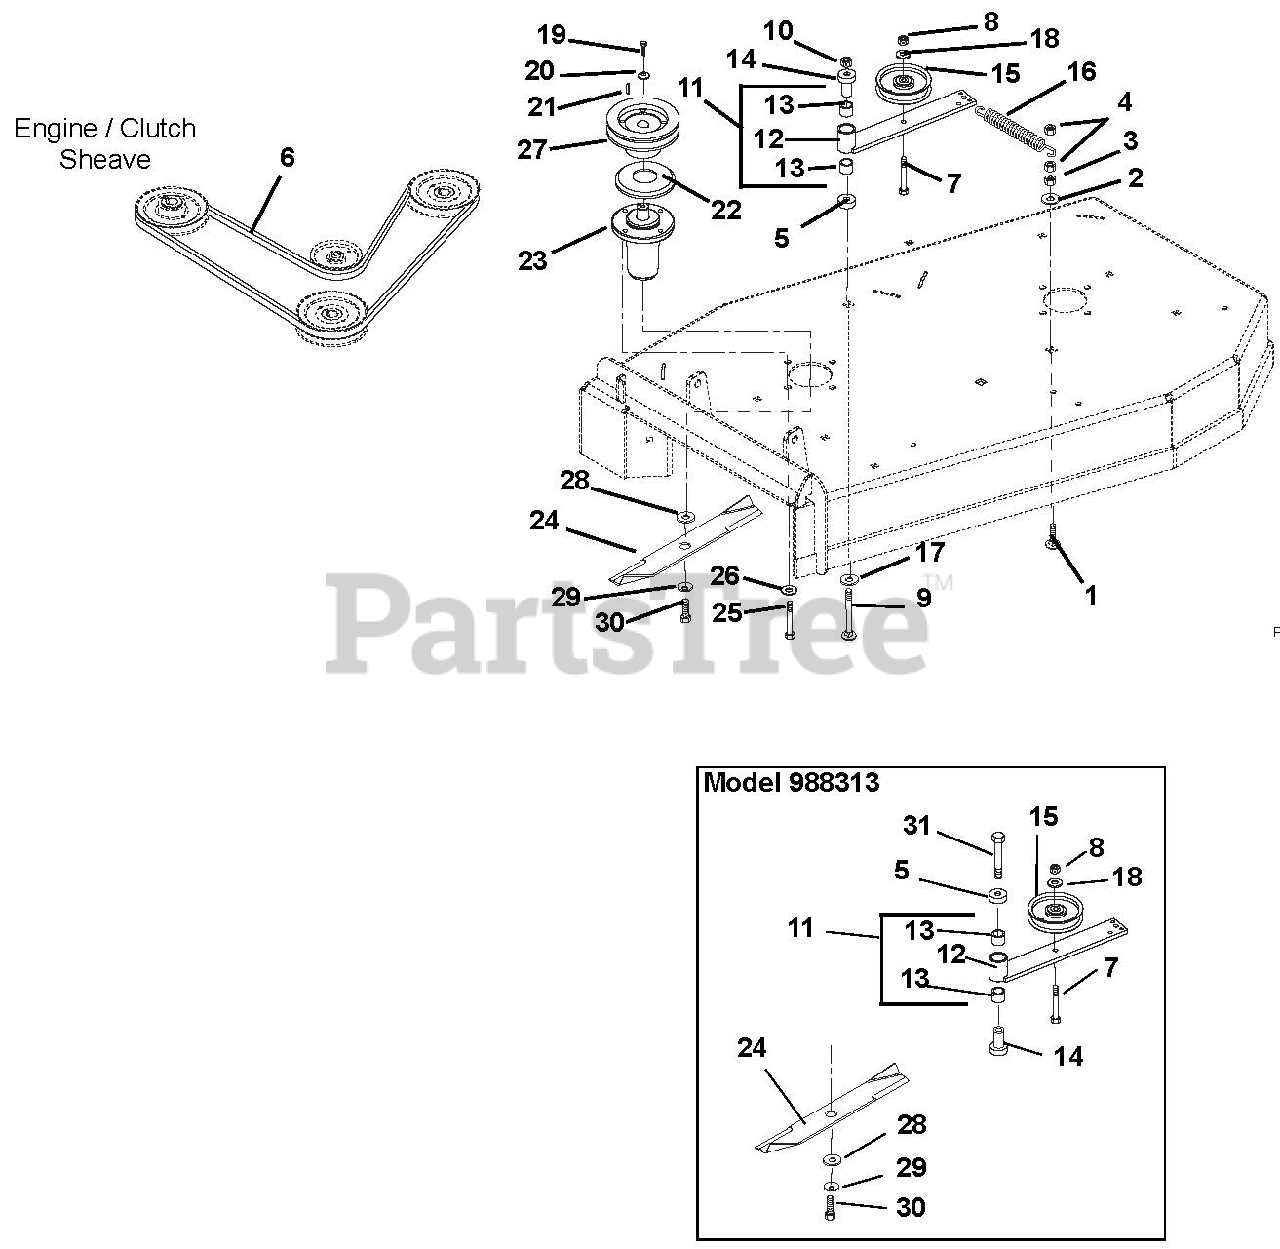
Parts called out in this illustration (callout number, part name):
1	Bolt-Round Head Square Neck .38-16 x 1.50 Grade 5
2	Washer-Locking .38 x .094 Regular
3	Nut-Hex .38-16
4	Nut-Locking-Center .38-16
5	Washer-Flat-Steel .515 x 1.625 x .25
6	V-Belt B-Section 36.70 x .650
6	V-Belt B-Section 35.47 x .650
7	Bolt-Round Head Square Neck .38-16 x 2.75 Grade 5
8	Nut-Locking-Center .38-16
9	Bolt-Round Head Square Neck .50-13 x 3.75 Grade 5
10	Nut-Locking-Center .50-13
11	Assembly, Idler Pivot Arm
12	Weldment, Idler Pivot Arm
13	Bearing, 1.00 x 1.12 x .75
14	Bearing, Pedestal Powdered Metal
15	Idler-Flat 4.00 x .38
16	Spring, Extension
17	Washer-Flat-Steel .755 x 1.375 x .062
18	Washer-Flat-Steel .375 x 1.125 x .065
19	Bolt-Hex .38-16 x 1.00 Grade 8
20	Washer-Cupped-Serrated .375
21	Key, Square .25 x .25 x 1.00 RC 40-50
22	Slinger-Dust
23	Assembly, Maintenance Free Spindle
24	Blade- Mower
24	Blade- Mulching
24	Blade, 32"
25	Bolt-Hex .38-16 x 1.00 Grade 5
26	Washer-Locking .38 x .094 Regular
27	Pulley
28	Washer, Flat .64 x 1.81 x .250
29	Washer-Bellville .63 x 1.625 x .14
30	Bolt-Hex .62-18 x 1.75 Grade 8
31	Bolt-Hex .50-13 x 3.75 Grade 5
